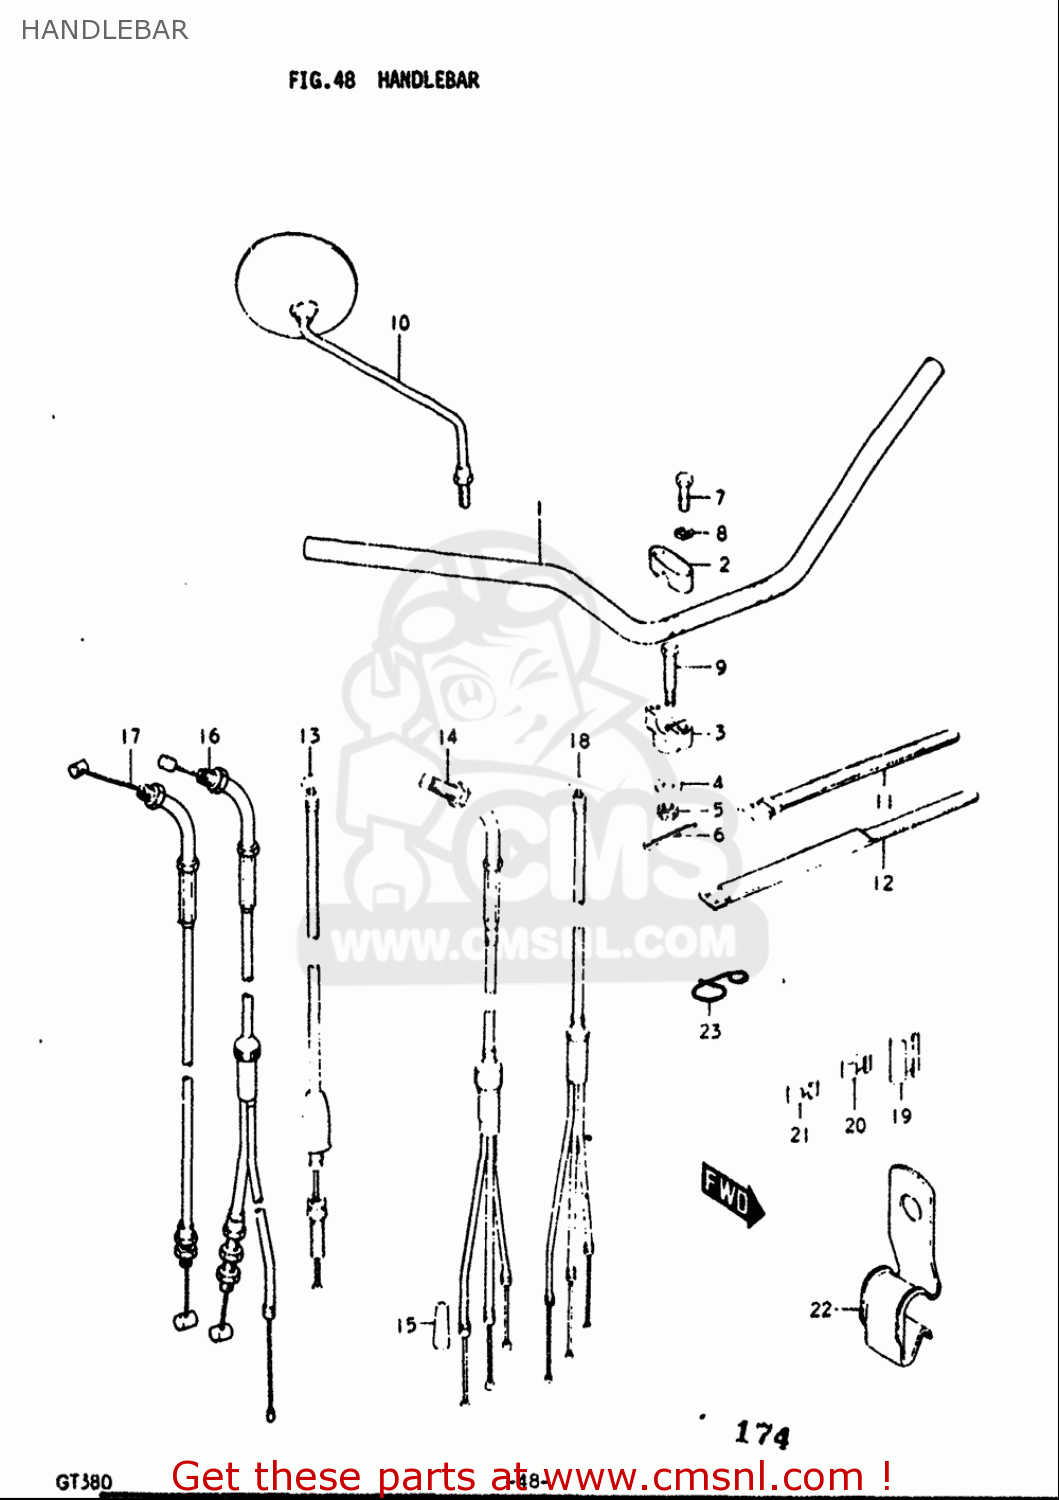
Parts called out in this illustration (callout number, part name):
1	HANDLEBAR
2	HOLDER,HANDLE UPR
3	HOLDER,HANDLEBAR LWR
4	WASHER(10.5X28X2.3)
5	NUT
6	PIN, COTTER
8	WASHER,LOCK
10	MIRROR ASSY,RE
11	CLAMP(L:120)
12	CLAMP(L:250)
13	WIRE,CLUTCH
14	CABLE ASSY,THROTTLE
15	SEAL,DUST(7X18X30)
16	CABLE ASSY,THROTTLE NO.1
17	CABLE ASSY,THROTTLE NO.2
19	CLIP
20	CLIP
21	GUIDE,CABLE
22	CLIP
